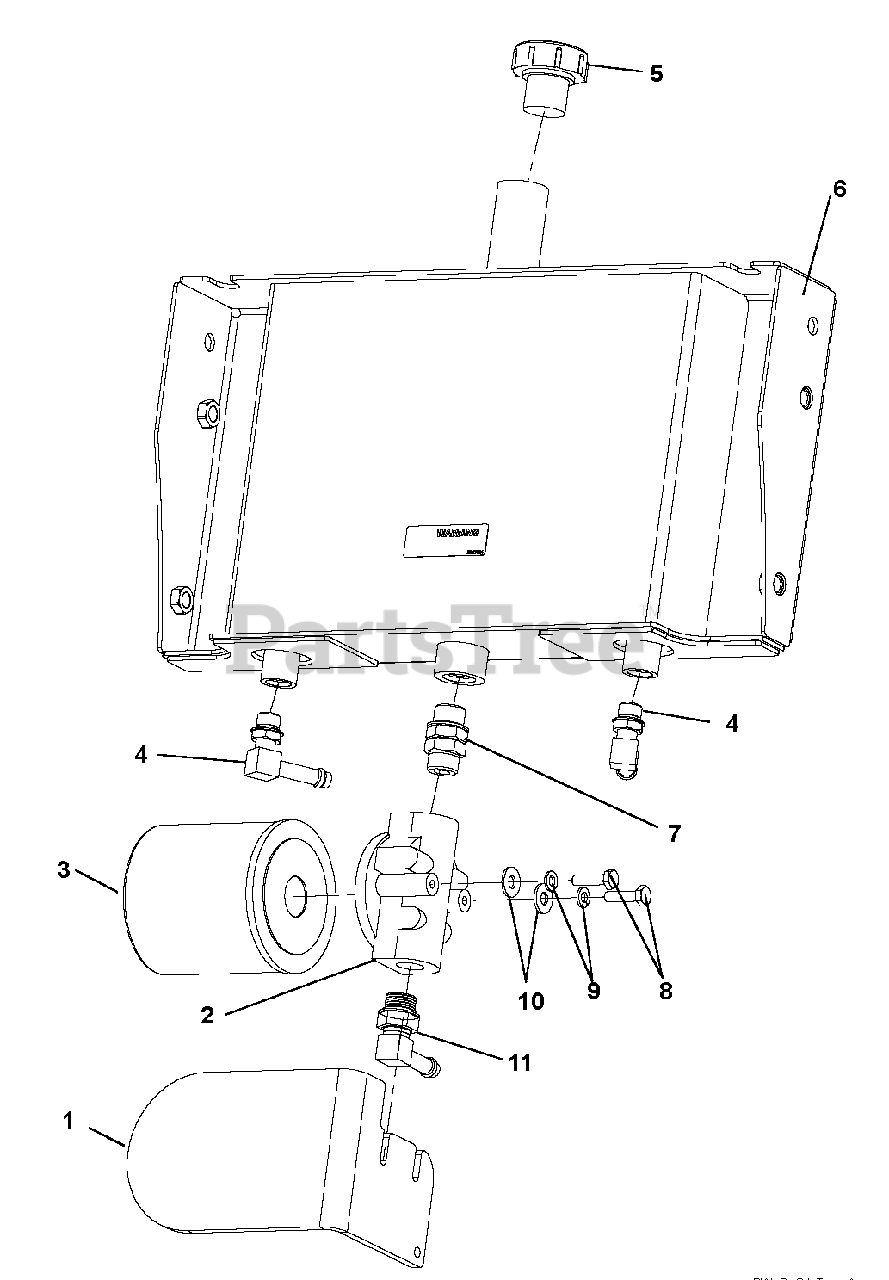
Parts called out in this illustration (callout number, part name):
1	Guard, Hydraulic Filter
2	Head, Oil Filter
3	Filter, Oil
4	Fitting, Hose 90 Deg. .5625 MOR x .375
5	Cap, Oil Fill Breather
6	Weldment, Tank
7	Straight Union SAE 8
8	Bolt .25-20 x 1.00 Hex Grade 5
9	Washer, .250 Medium Spring Lock
10	Washer, .250 Regular Flat
11	Fitting, 90 BRB-OR
